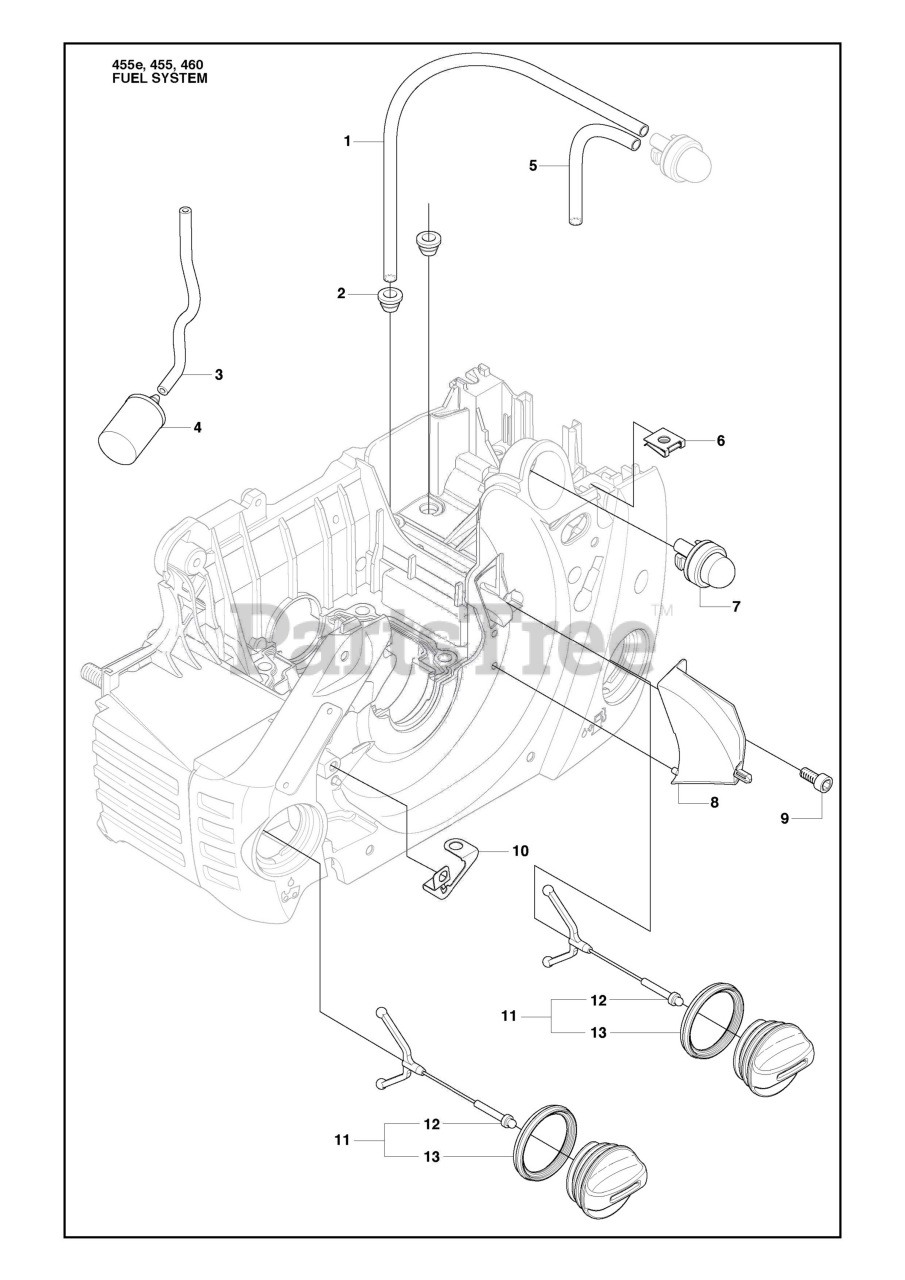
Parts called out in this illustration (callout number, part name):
2	FUEL TANK BUSHING
3	FUEL HOSE
4	FUEL FILTER
5	FUEL HOSE/38MM
7	AIR PURGE BUBBLE
10	SWITCH PLATE
11	TANK CAP
